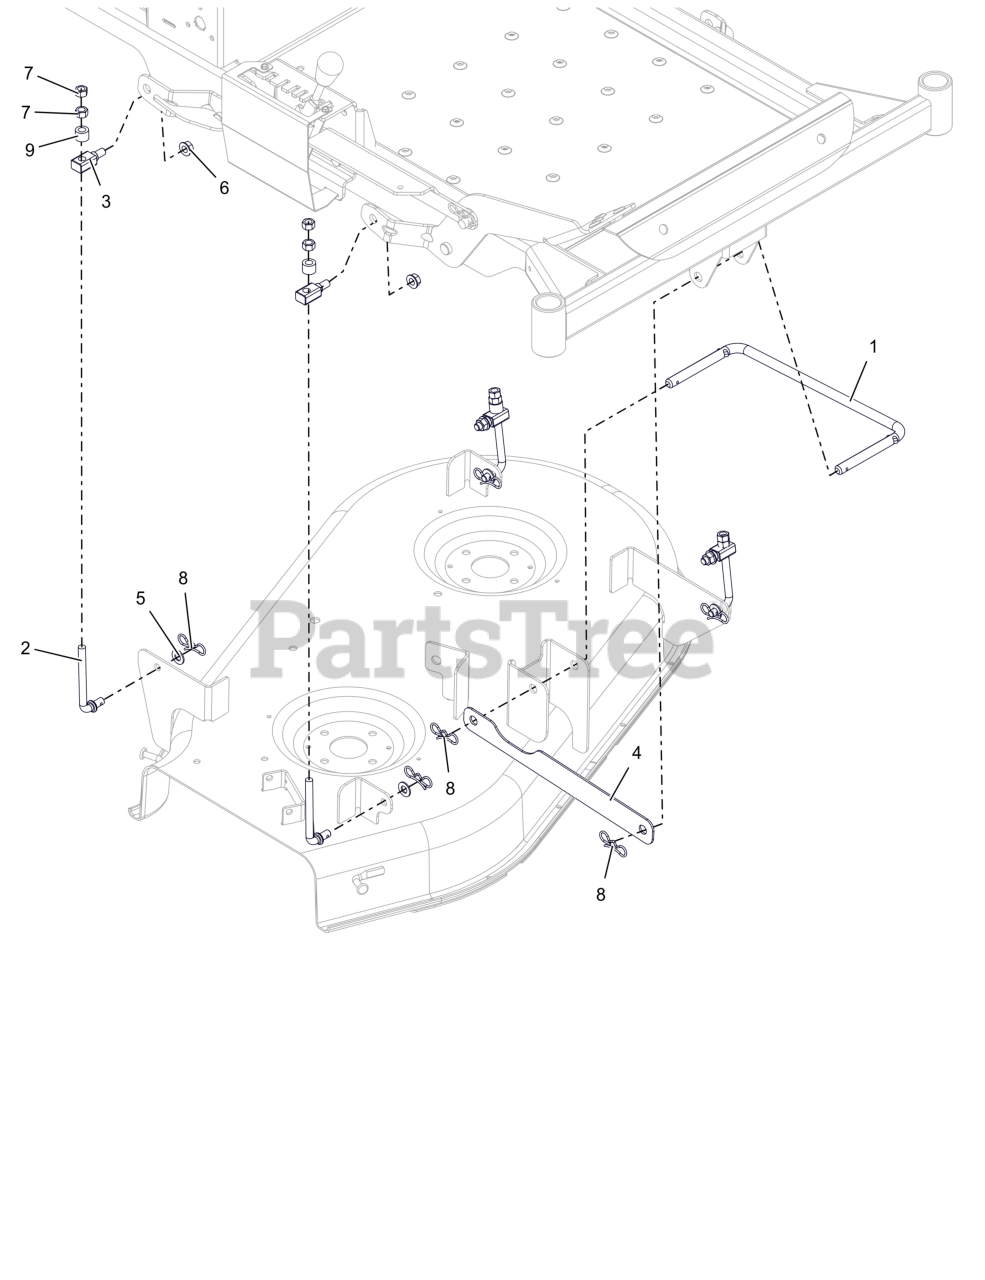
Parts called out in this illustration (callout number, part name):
1	WIREFORM, DRAG LINK
2	WIREFORM, DECK ADJUSTMENT
3	TRUNNION- DECK LIFT
4	STRAP, DRAG LINK
5	WSHR,FLT .406X.812X.065 ZCC
6	NUT-LK-CTR-FLG .375-16 GF ZCC
7	NUT-STD .375-16 G2 ZCC
8	PIN, BOWTIE .091X1.875 ZCC
9	BSHG-SLV .391X.688X.52 PM
